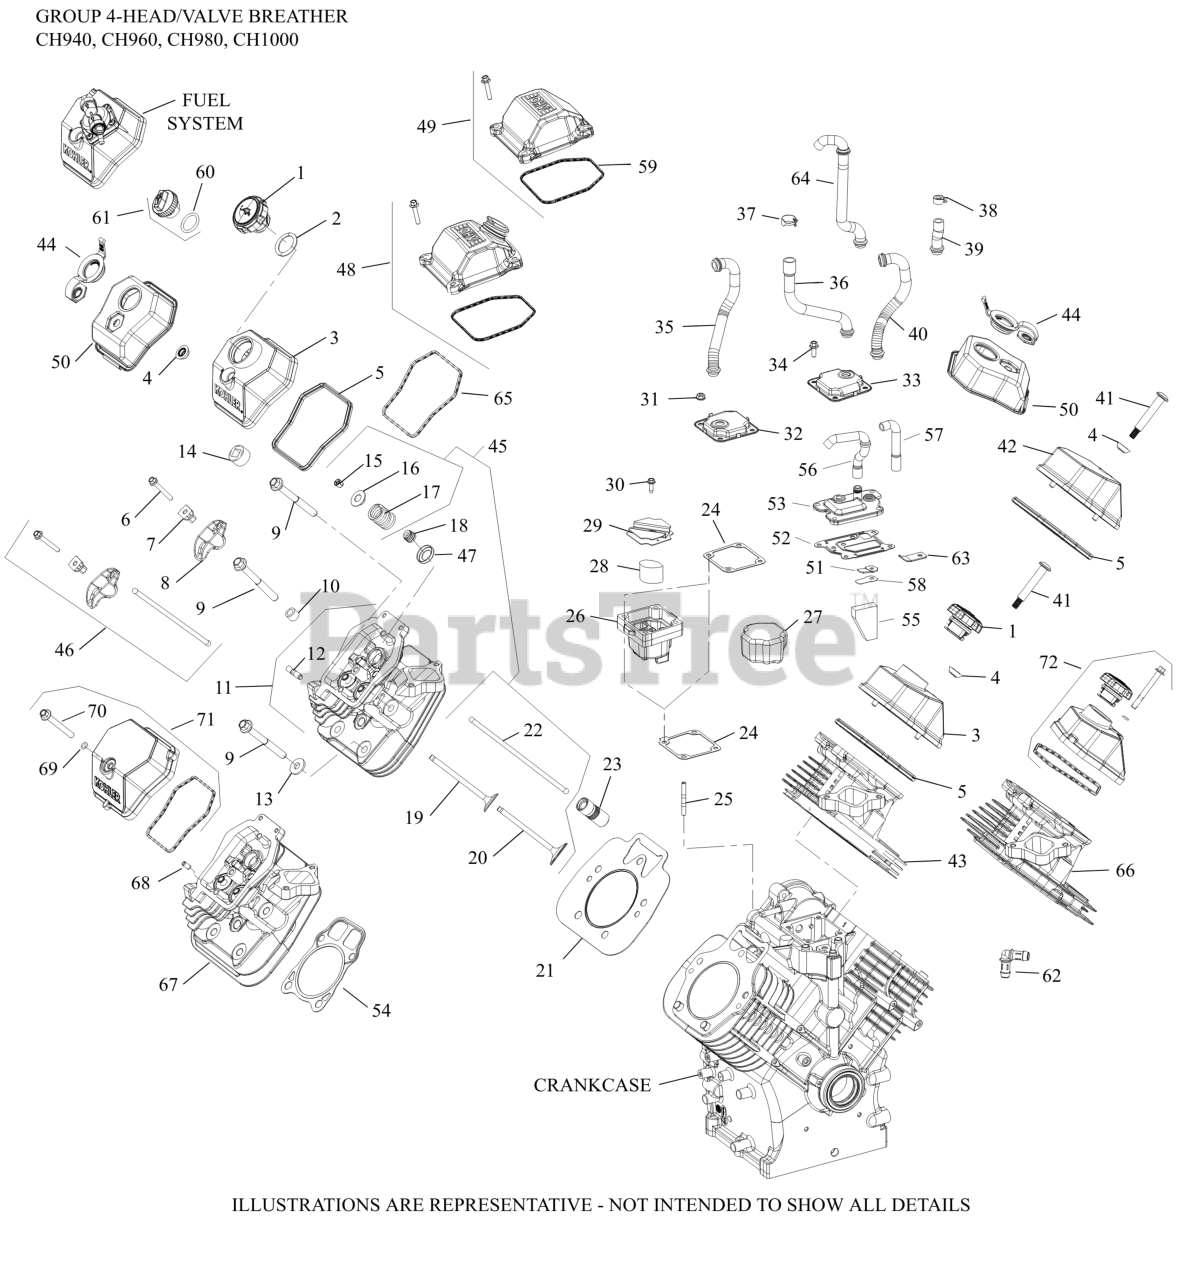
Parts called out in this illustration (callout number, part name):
1	CAP ASSEMBLY
3	KIT, COVER, VALVE (OIL FILL)
4	GROMMET, VALVE COVER SCREW
5	SEAL, VALVE COVER-USE 62 032 20-S
6	SCREW, FLG M6X1.0X45-USE 25 086 764-S
7	PIVOT, ROCKER ARM
8	ARM, ROCKER
9	SCREW, FLG M10X1.5X90
11	HEAD CYLINDER #2-USE 62 318 43-S
13	WASHER, FLAT 13/32"
14	PLUG, PIPE 3/4 NPTF SQUARE
15	KIT, RETAINER
16	CAP, VALVE SPRING
17	SPRING, VALVE
18	SEAL, VALVE BAND
19	VALVE, EXHAUST
20	VALVE, INTAKE
21	KIT, CYLINDER HEAD GASKET
22	ROD, PUSH
23	LIFTER, VALVE HYDRAULIC-USE 25 351 11-S
24	GASKET, BREATHER
27	FILTER, BREATHER
33	KIT, BREATHER ASSEMBLY
34	SCREW, THREAD FORMING
40	HOSE, BREATHER H/S
41	SCREW, SHOULDER
43	HEAD CYLINDER #1-USE 62 318 42-S
